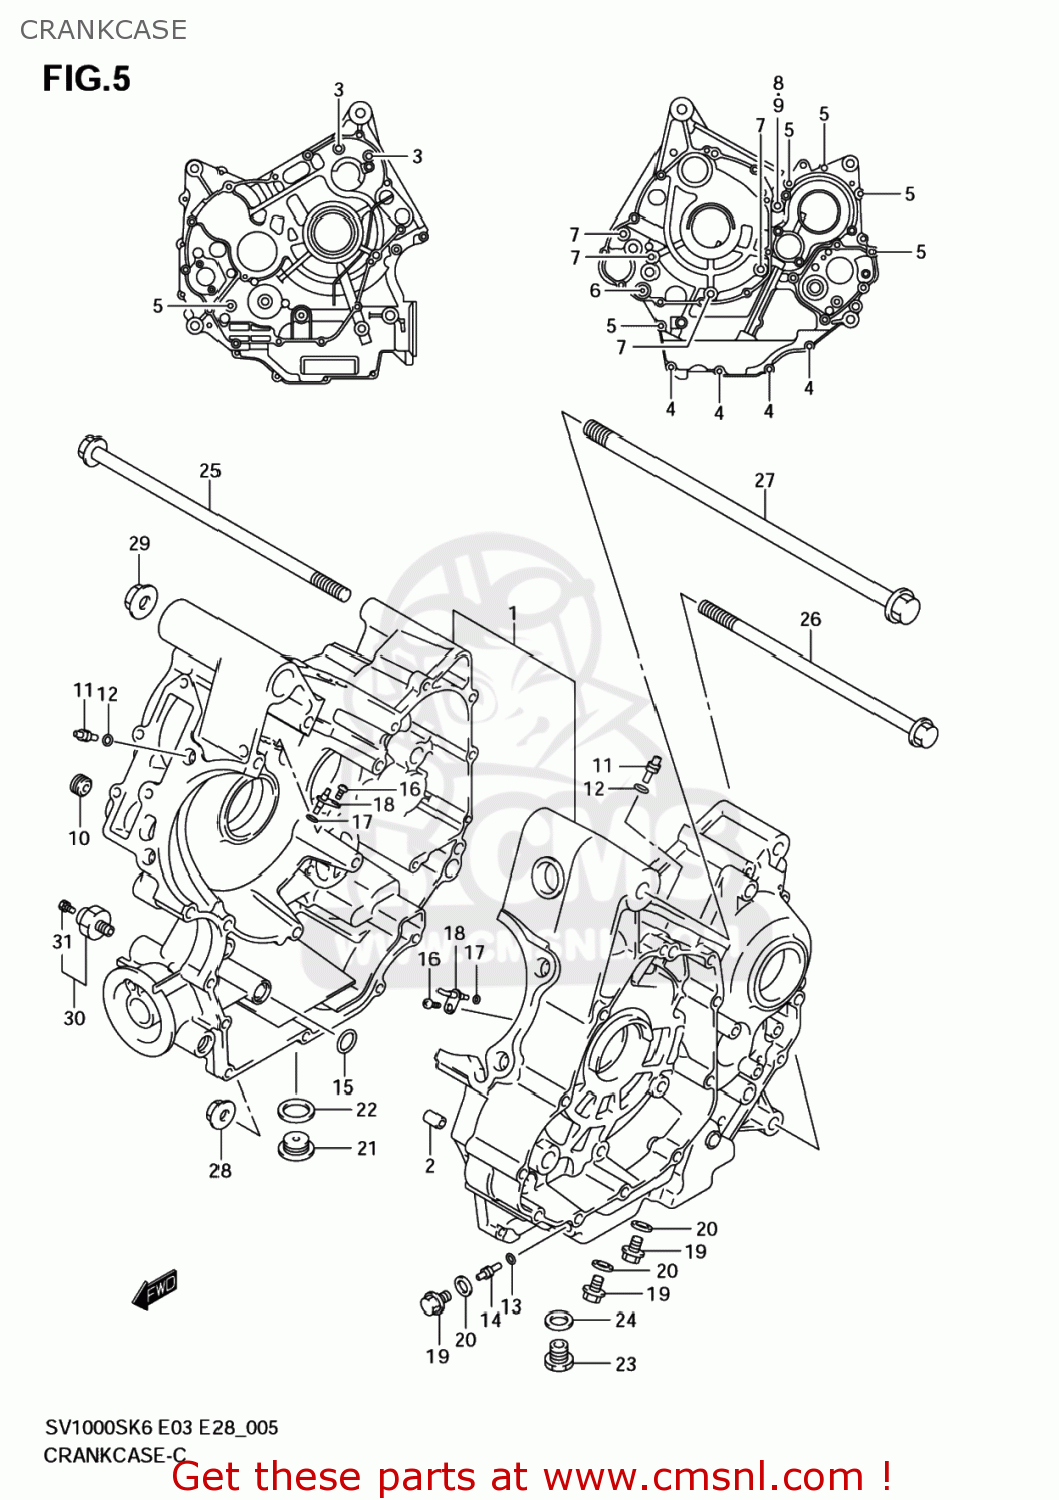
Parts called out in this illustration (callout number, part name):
1	CRANKCASE SET
2	PIN,CRANKCASE
3	BOLT(8X110)
4	BOLT,G/S SWITC
5	BOLT
6	BOLT, CRANKCASE (6X85)
7	BOLT
8	BOLT(8X125)
9	WASHER
10	JET,OIL GALLERY(3.6)
11	JET,AIR(14)
12	O RING(D:1.2,ID:4)
13	O RING(D:1.9,ID:12.6)
14	JET,OIL GALLERY
15	O RING(D:1.2,ID:4)
16	BOLT(6X12)
17	O RING(D:1.2,ID:4.7)
18	JET,PISTON COOLING
19	BOLT
20	GASKET(8.2X14X1) (NAS)
21	PLUG,16X8
22	GASKET(16X22X2) (NAS)
23	PLUG(14X20)
24	GASKET(13.8X18.8X4.8) (NAS)
25	BOLT(10X225)
26	BOLT(10X255)
27	BOLT(12X320)
28	NUT
29	NUT
30	SWITCH ASSY,OIL PRESSURE
31	BOLT,OIL PRESSURE SWITCH
